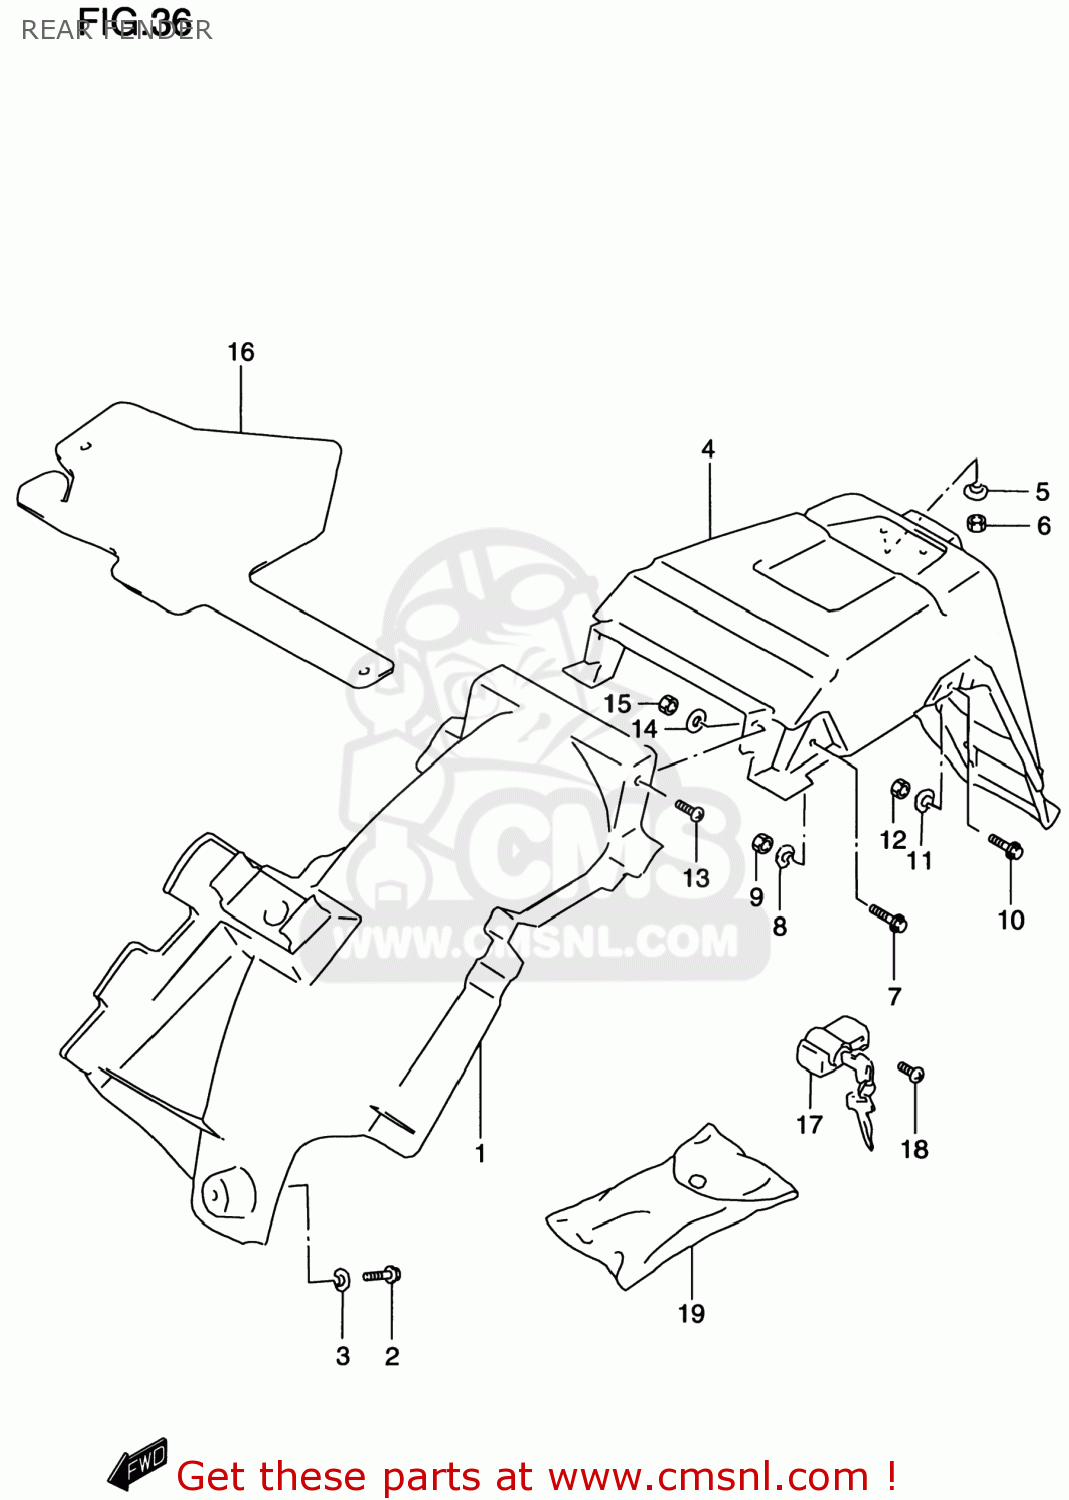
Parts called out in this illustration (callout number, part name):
1	BODY COMP,REAR FENDER
2	BOLT
3	WASHER
4	BODY ASSY,RR FENDER RR
5	WASHER
6	NUT
7	BOLT
8	WASHER
9	NUT
10	BOLT
11	WASHER
12	NUT
13	SCREW
14	WASHER(6.5X18X1.6)
15	NUT
16	MUDFLAP,RR FENDER FR
17	LOCK SET,HELMET
18	SCREW(6X14)
19	TOOL ASSY
